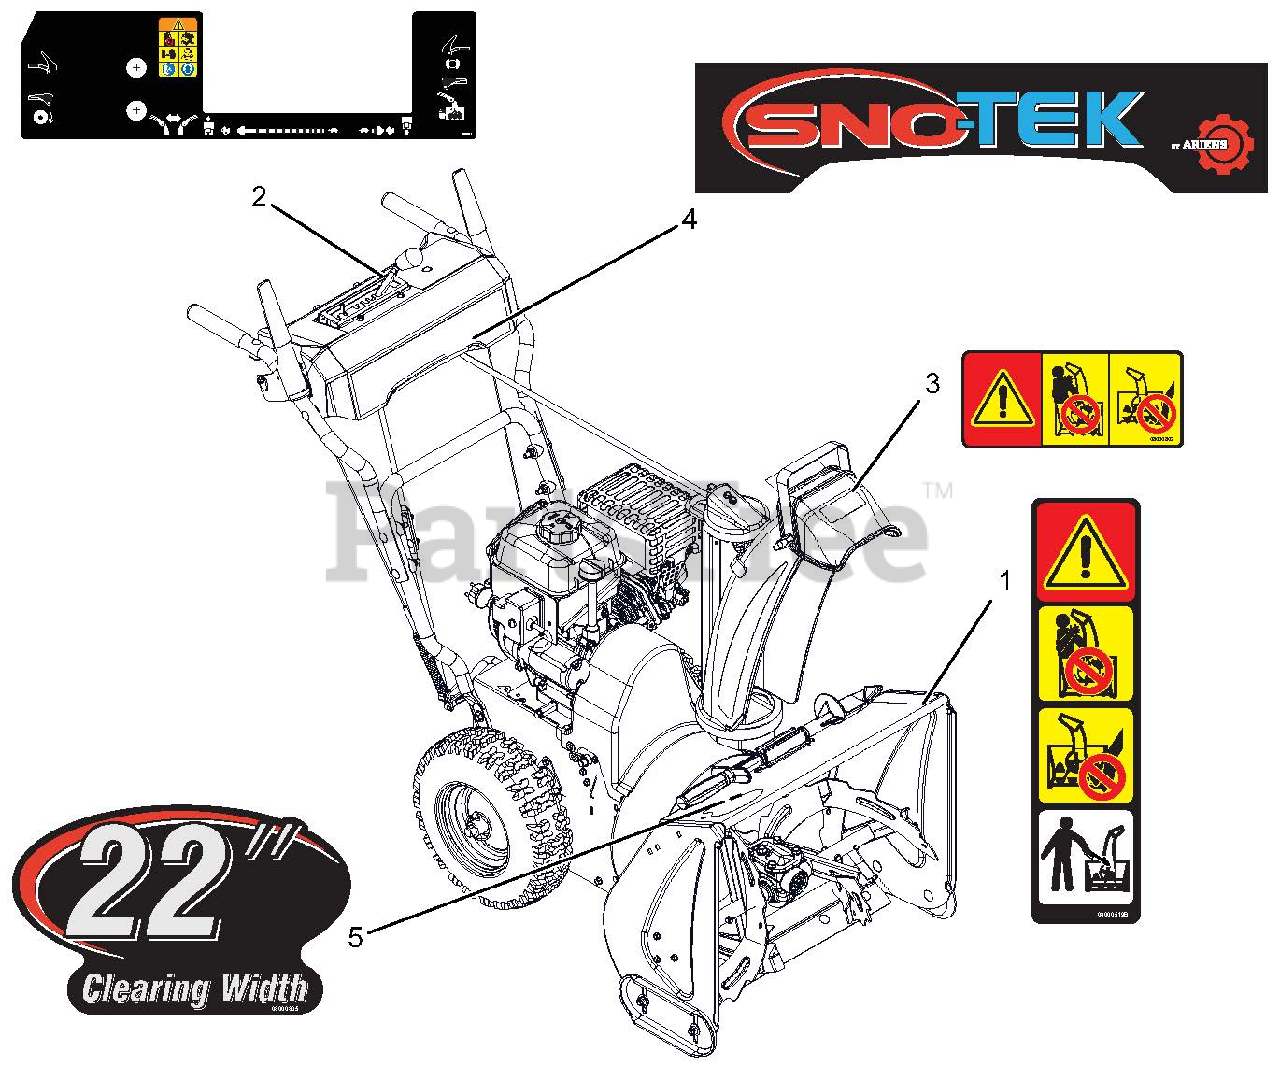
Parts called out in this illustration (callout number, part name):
1	DECAL, DANGER - ROTATING PARTS
2	DECAL,CONTROL - COMPACT MANUAL
3	DECAL, DANGER SNO-TEK
4	DECAL, DASH - SNO-TEK
5	DECAL, HOUSING SNO-TEK 22
